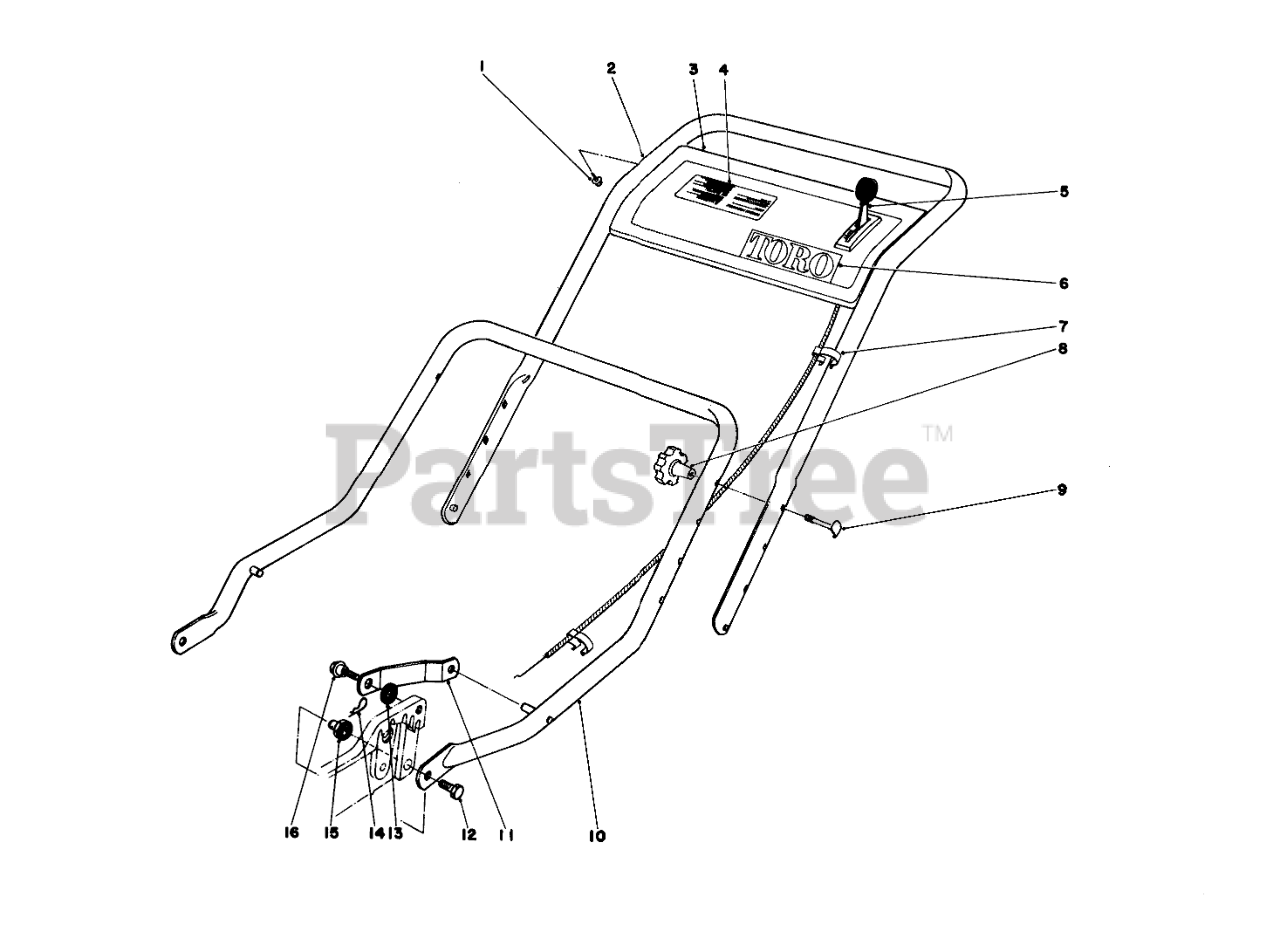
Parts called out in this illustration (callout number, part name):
1	SCREW-HWHTF
2	Upper Handle
3	Control Plate
4	Decal-Control Plate
5	Control-Throttle
6	TORO LOGO DECAL
7	BOWDEN CLIP
9	HANDLE SCREW
10	Lower Handle
11	HANDLE LATCH
12	SCREW-HH
13	SPACER
14	PIN-COTTER, HAIR
15	HANDLE PIVOT NUT
16	SCREW-SHOULDER
